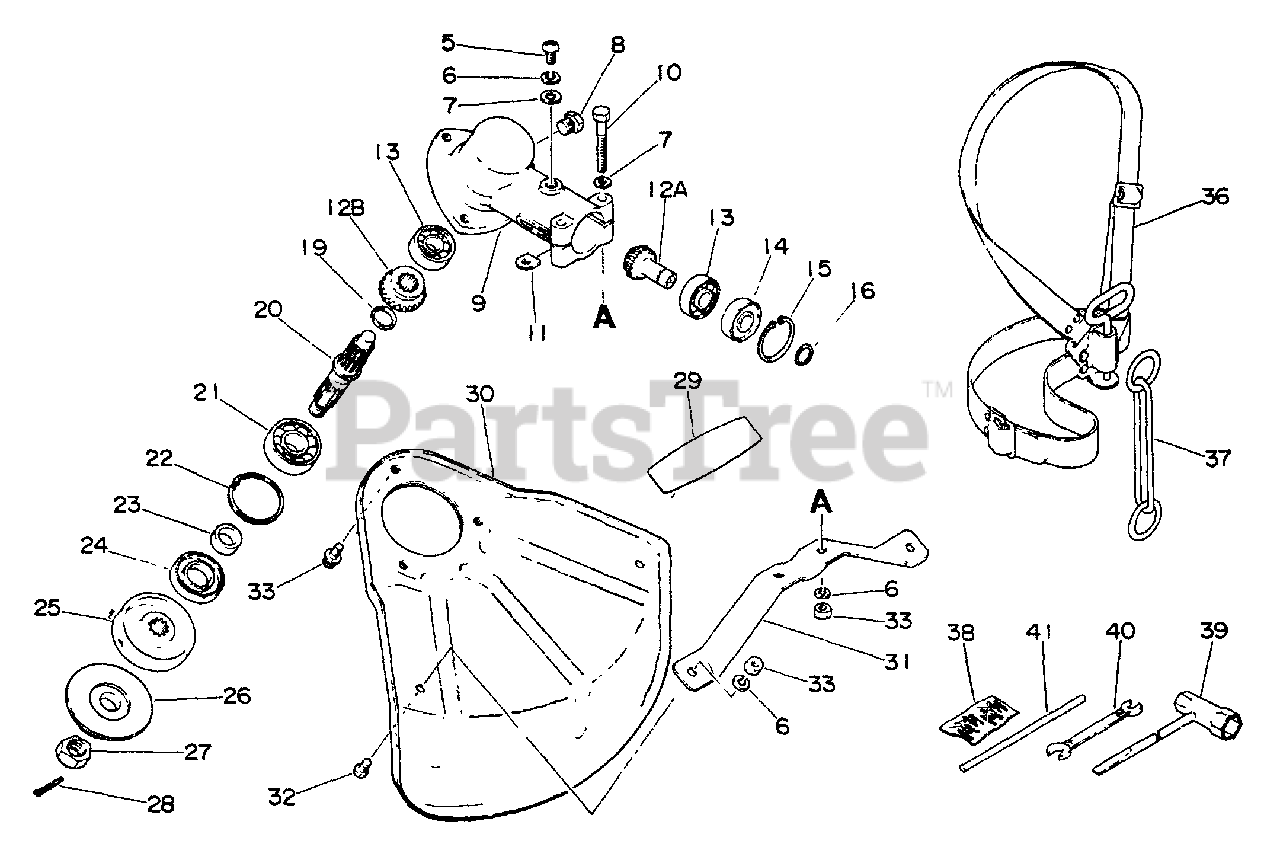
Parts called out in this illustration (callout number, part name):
5	SCREW 5×10
6	WASHER, SPRING 5
7	WASHER, FLAT 5.5×10×0.8
8	BOLT 8×8 SP
9	CASE, GEAR
10	BOLT 5×35 SP
12	GEAR SET
12A	GEAR SET
12B	GEAR SET
13	BEARING, BALL 609
14	BEARING, BALL 609
15	RING, SNAP Ø25
16	RING, RETAINING
19	RING, RETAINING - 12
20	SHAFT, GEAR
21	BEARING, BALL - 6201 C3
22	RING, SNAP Ø32
23	SPACER 11.8×15×9
24	SEAL, OIL
25	PLATE, ADAPTER - UPPER
26	PLATE, ADAPTOR - LOWER
28	PIN, COTTER 2×22
29	LABEL - ECHO
30	SHIELD ASSY
31	BRACKET, SHIELD MOUNTING
32	SCREW 5×8
33	NUT M5
36	SHOULDER STRAP ASSY
37	HOOK
38	PIN, COTTER 2×22 (PKG. OF 10)
39	T-WRENCH
40	SPANNER 8×10
41	TOOL, LOCKING 5×120 MM
